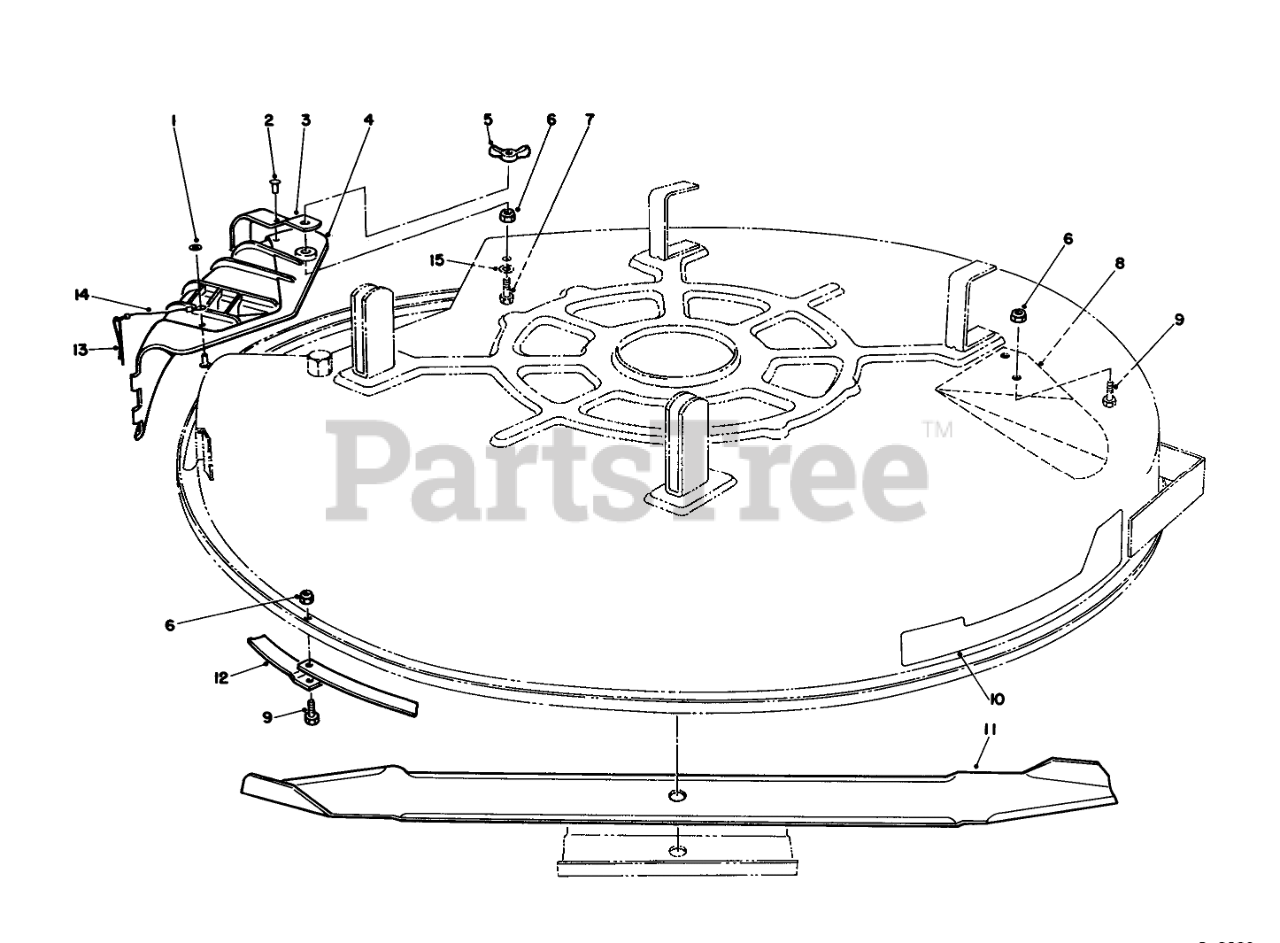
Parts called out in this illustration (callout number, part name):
1	WASHER-PLAIN
2	RIVET-BLIND
3	Brace-Cover, Rear
4	Assy.-Cover, Discharge (Incl. Ref. #1, 2, 13 & 14)
5	NUT-WING
6	NUT-LOCK, NI
7	SCREW-HH
8	Kicker
9	SCREW-HH
10	DECAL/RECYCLER 32" BACK
11	BLADE-RECYCLER
12	RING-DECK
13	PIN-LOCKING, CHUTE
14	LANYARD
15	WASHER-PLAIN
